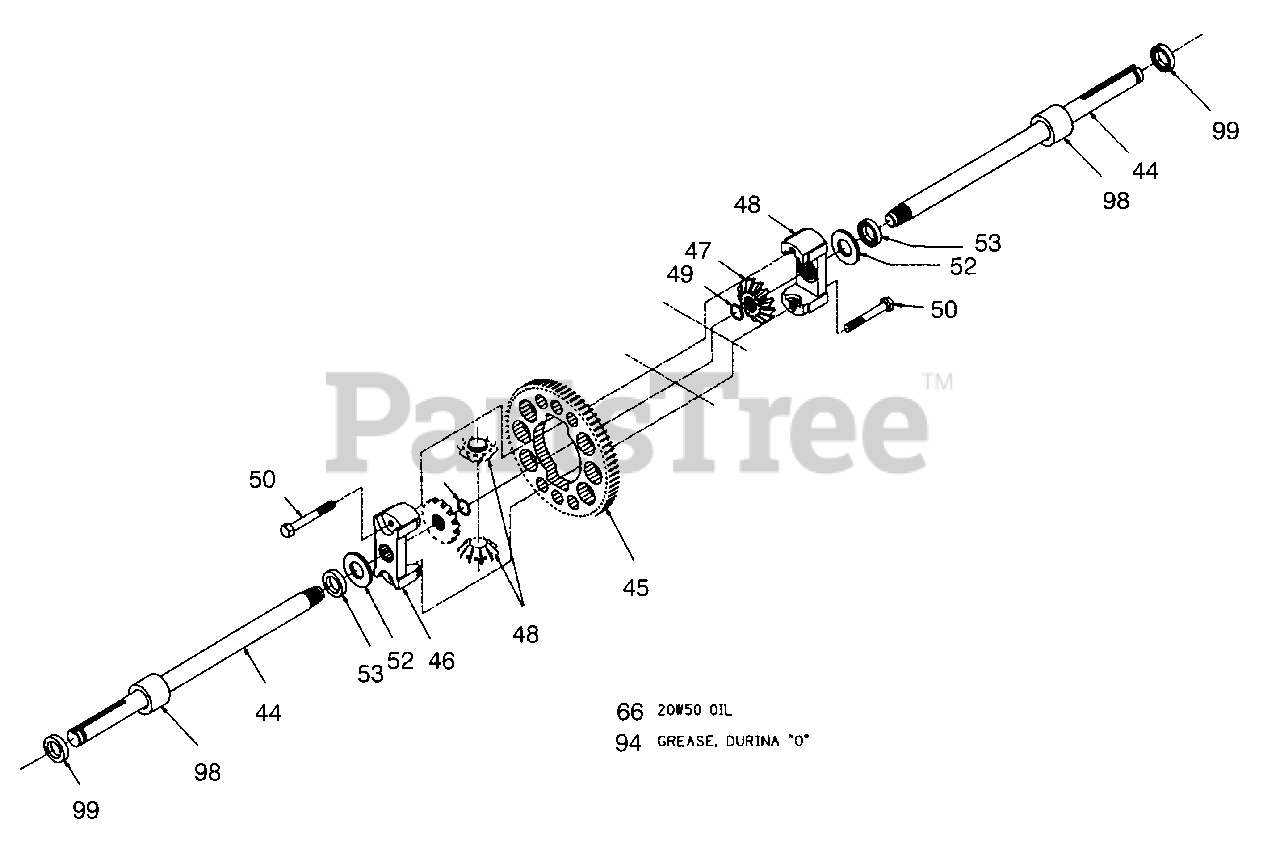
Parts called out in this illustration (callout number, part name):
26	Plate-Bypass
44	Shaft-Axle
46	Housing-Diff.
49	Ring-Retaining
50	Bolt-Diff. Locking
52	Washer
53	Seal
66	Oil (.5675)
94	Grease Durina "O"
98	Sleeve-Bearing
99	Seal-Wiper
